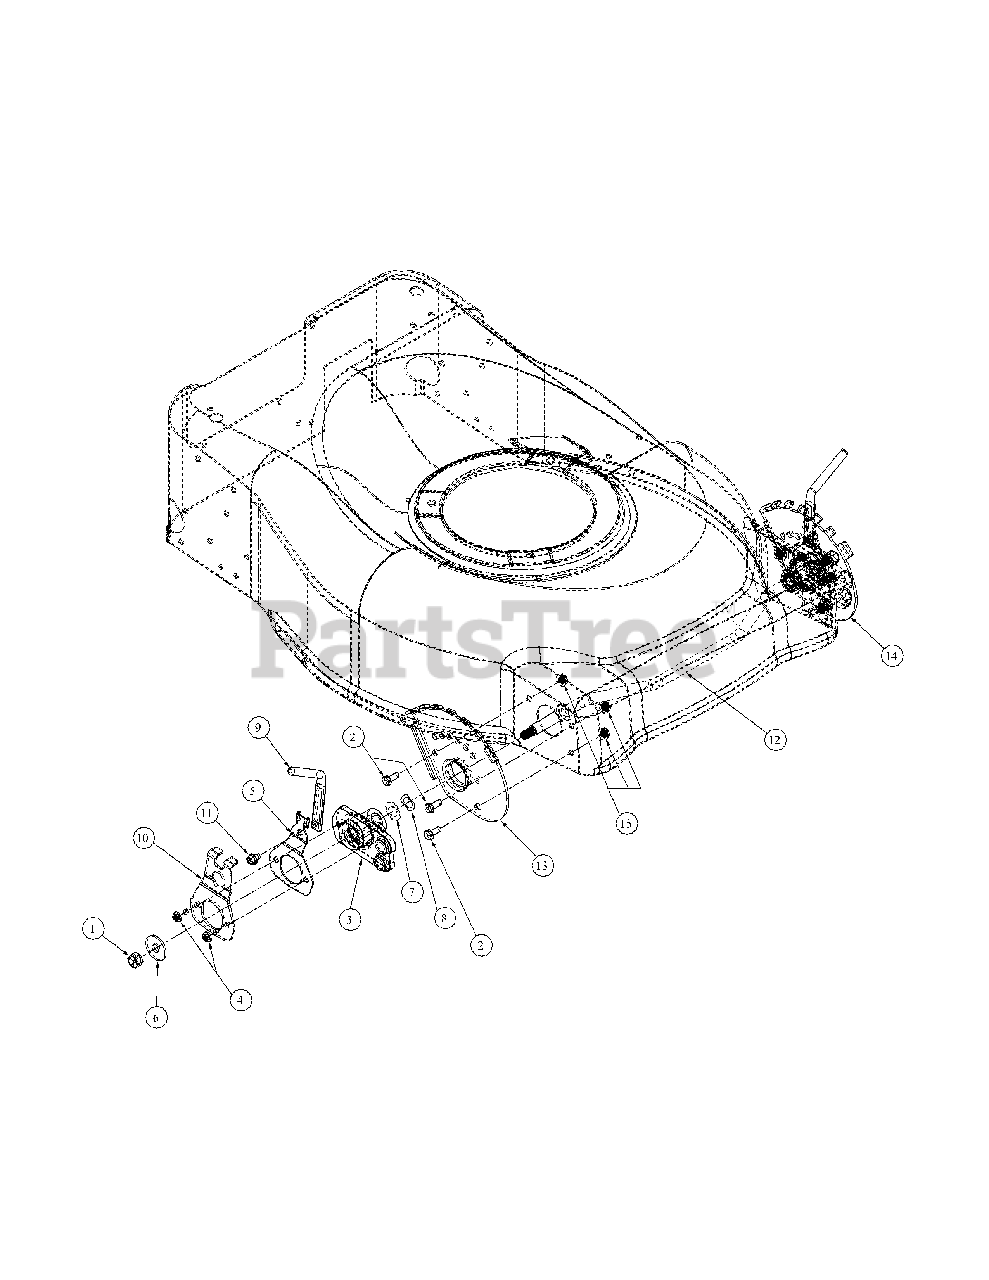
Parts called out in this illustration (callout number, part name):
1	L-Nut, 3/8-16, NYL INS. GR A. Z
2	HHCS, 1/4-20, .620, GR5, Standard
3	Pivot Wheel Bracket Assembly, 2 POS
4	Screw, TT, 1/4-20, 0.625, PANTRXI
5	Plate, Spring Height Adjuster
6	Flat Washer, .411 x 1 .25 x .100
7	Flat Washer, .536 ID x .930 OD x .05
8	Wave Washer, .531 IDX .781 ODX .01
9	Height Adjustment Handle
10	Spring Lever Support Bracket
11	Screw, TT, 1/4-20, 0.375, Hex Indicator Washer
12	Front Axle, .500 OD
13	Height Adjustment Bracket, Right Front
14	Height Adjustment Bracket, Left Front
15	Nut, 1/4-20, Hex Flange, Lock, Group F
